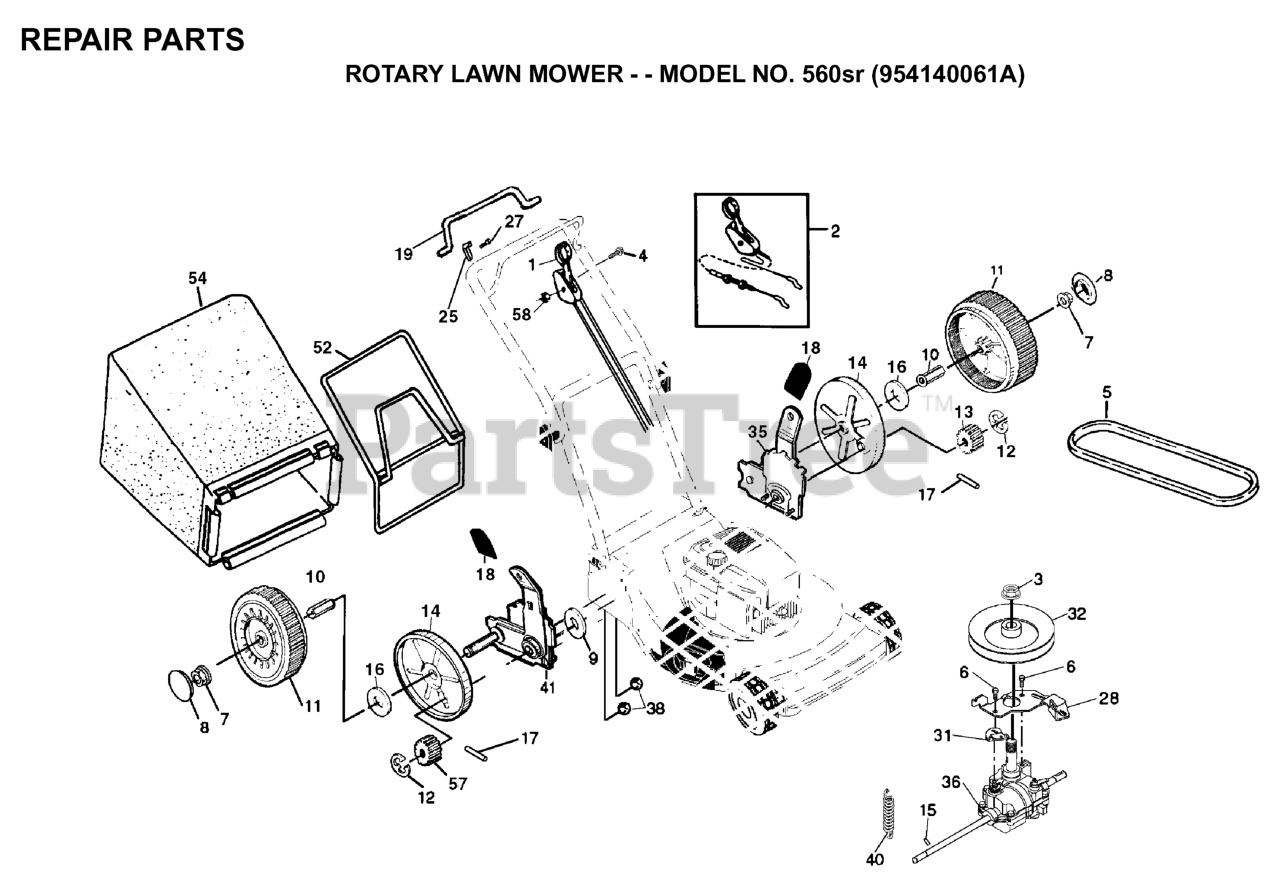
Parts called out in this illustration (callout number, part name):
1	SPEED CONTROL
2	KIT/HEAD CONTROL
3	METRIC NUT
4	SCREW 1/4-20 X 2.12
5	DRIVE BELT
7	NUT
8	HUBCAP.8".GREY
9	THRUST WASHER
10	BUSHING PM
12	E-RING 7/16 RE
13	DR PINION LH
14	DUST SHROUD PM
15	PIN.SPRING.THRUST
16	WASHER FLUT
17	DRIVE PAWL
18	SELECTOR KNOB
19	DRIVE CONTROL BAR
25	UPSTOP BRACKET
27	TAPPING SCREW
36	TRANSMISSION
38	NUT
52	CATCHER.FRAME.WALK
54	GRASS BAG
57	DR PINION RH
58	LOCK NUT
